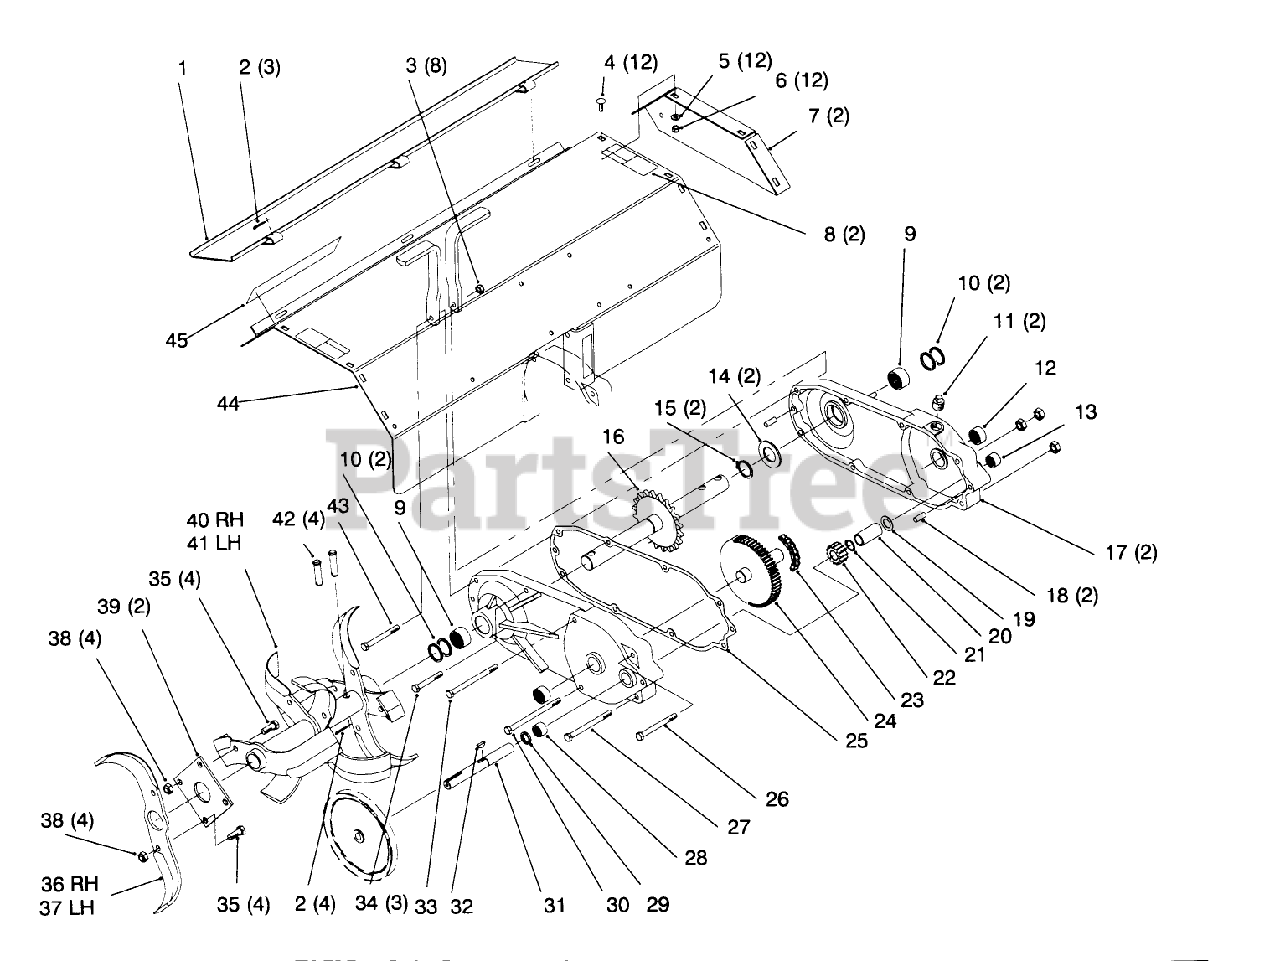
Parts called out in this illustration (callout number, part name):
1	GUARD ASM
2	PIN-COTTER
3	NUT-LOCK, NI
4	BOLT-CARR
5	WASHER-PLAIN
6	NUT-LOCK, NI
7	COVER-TINE END
8	DECAL-DANGER
9	BEARING-NEEDLE
11	PLUG-PIPE, SQH
12	BEARING-NEEDLE
13	BEARING-NEEDLE
14	WASHER
15	RING-RETAINING
16	TINE SHAFT ASM
17	GEAR CASE TILLER RED
18	PIN-ROLL
19	WASHER-THRUST
20	TUBE-SPACER
21	Ring-Snap
22	GEAR-PINION
23	CHAIN
24	GEAR AND SHAFT ASM
25	GASKET-TRANSMISSION
26	SCREW-HH
27	SCREW-HH
28	BEARING-NEEDLE
29	SEAL-OIL
30	SCREW-HH
31	SHAFT-INPUT
32	KEY-WOODRUFF
33	SCREW-HH
34	SCREW-HH
35	SCREW-HH
36	Tine-RH
37	Tine-LH
38	NUT-LOCK, NI
39	PLATE-TINE MTG RED
40	Tine-RH
41	Tine-LH
42	PIN-CLEVIS
43	SCREW-HH
44	Shield/Decal Asm (Incl. Rfe. #8)
45	DECAL-ATTACHMENT
